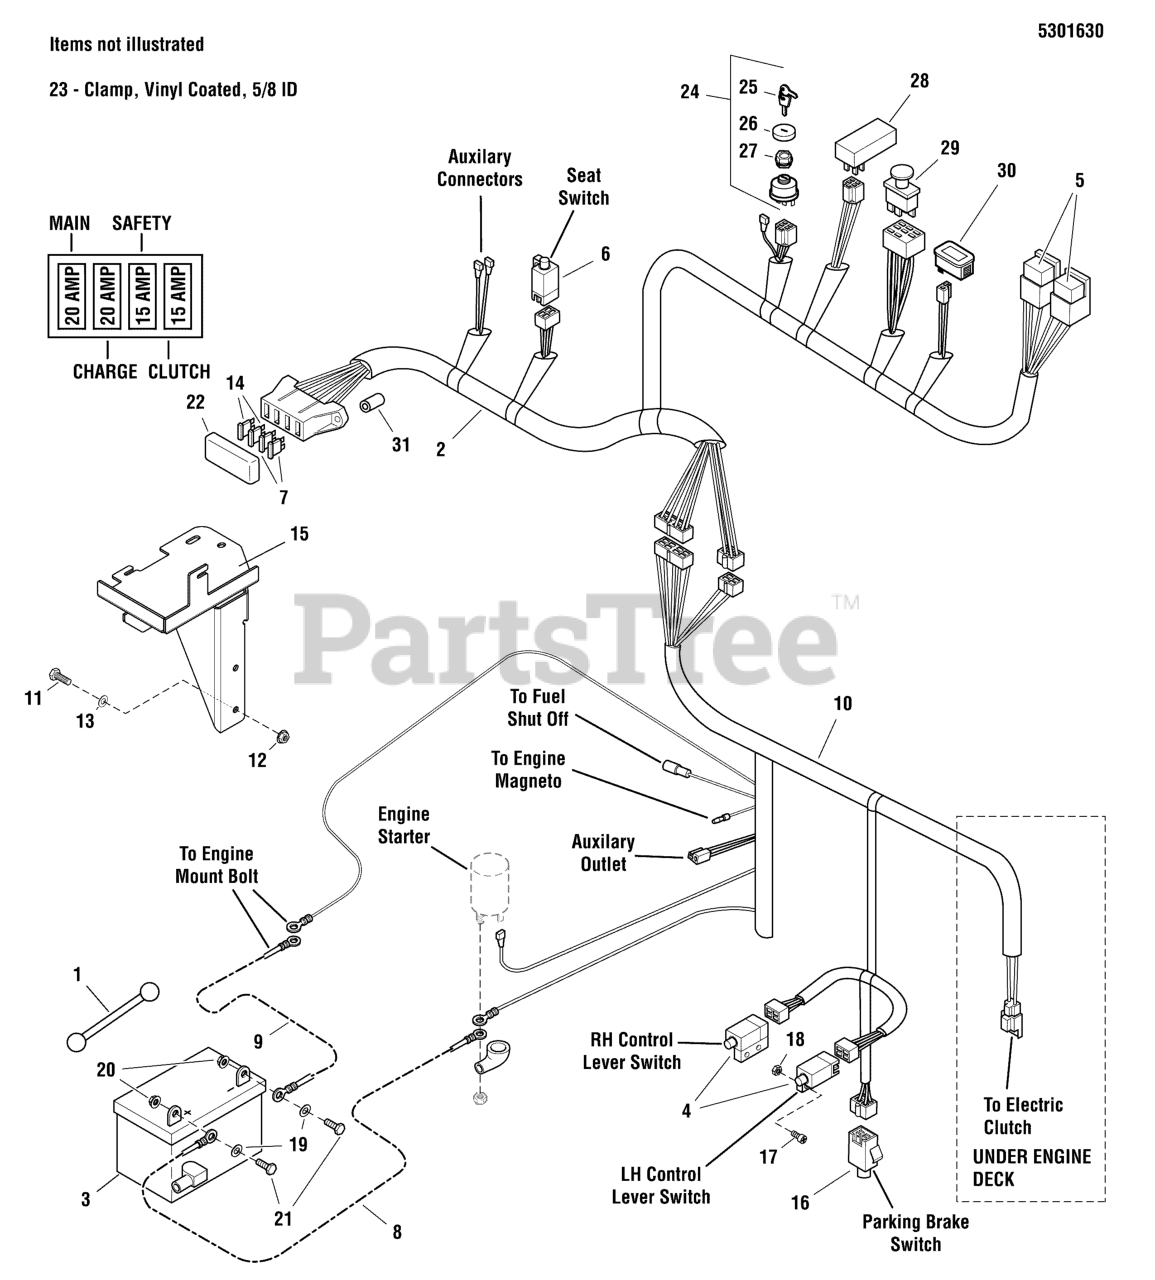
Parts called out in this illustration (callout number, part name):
1	STRAP-BLACK RUBB
2	WIRE HARNESS, OPERATOR COMPARTMENT, EVO
3	BATTERY, WET (BCIU1, 340 CCA)
4	SWITCH, PLUNGER, N.O.
5	RELAY, 12V, 40A
6	SWITCH, PLUNGER, NO/NO BOLT-ON
7	FUSE, ATO-15 (15 AMP)
8	BATTERY CABLE, POSITIVE, 30"
9	BATTERY CABLE, NEG, 22, 1/4-5/16
10	WIRE HARNESS, MAIN, EVO 48 (48" MODELS)
11	BOLT, 3/8-16 X 1" GD5 CZ
12	NUT, 3/8-16 HEX NYLOCK FLANGE
13	WASHER, 3/8 SAE
14	FUSE, ATO, 20 AMP
15	WELD, BATTERY MOUNT - RED (48" MODELS)
16	SWITCH, DP NO/NC SNAP-IN
17	SCREW- #10-24 X 1/2 ROUND PHILLIPS
18	NUT, #10-24 HEX NYLON LOCK
19	WASHER, 1/4 SAE
20	NUT, 1/4-20 HEX NYLOCK FLANGE
21	BOLT, 1/4-20 X 3/4 GD5 YZ
24	SWITCH, IGNITION, 6 POST
25	KEY, IGNITION MOLDED SET
26	COVER, PLASTIC, SNAP ON
27	PLASTIC NUT
28	MODULE, TIME DELAY
29	SWITCH, BLADE ENGAGEMENT
30	HOUR METER
31	SPACER, .20 X .38 X 1.25
